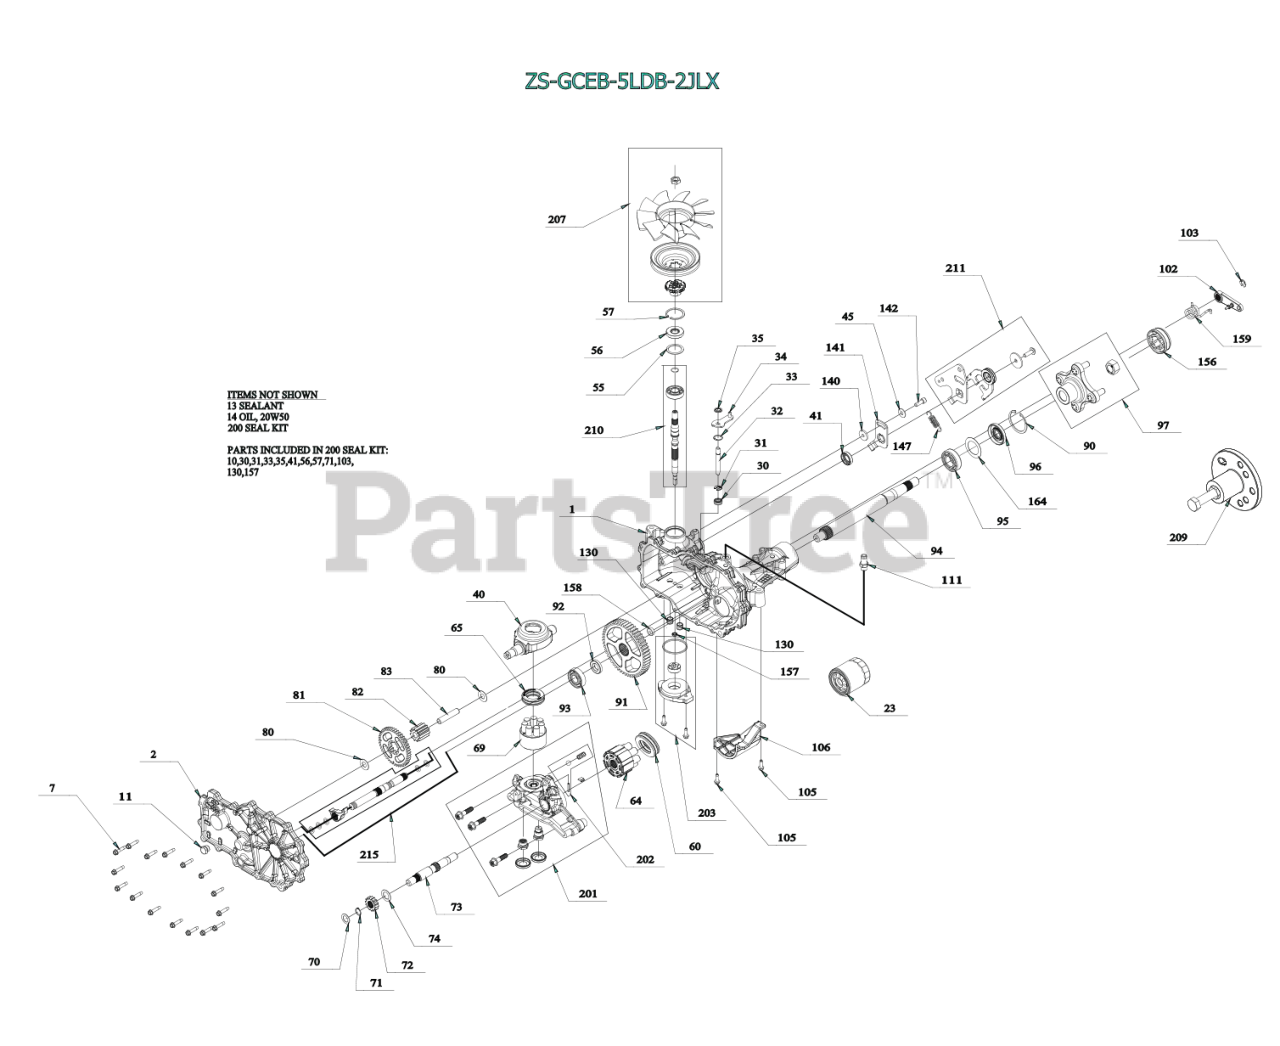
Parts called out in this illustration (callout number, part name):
1	KIT, MAIN HOUSING, RH, CHARGE, CONTROL
2	KIT, SIDE COVER RH
7	SCREW,HEX WASHER 1/4-20X1.125
23	OIL FILTER, TRANSMISSION
30	SEAL, LIP .375X.75X.25
31	RING. RETAINING
33	RING, RET .750
34	ARM, BYPASS
35	RING, RTNG .
40	TRUNNION, SWASHPLATE
41	SEAL, LIP 18X32X7
45	WASHER
55	WASHER 1.23X1.56X.04
56	SEAL, LIP 17X40X7
57	RING, RET 1.56 INT
60	HG THRUST BEARING (51462)
64	HG 16CC CYLINDER BLOCK (71579)
65	HG THRUST BLOCK (53502)
69	HG SEVEN PISTON BLOCK (71971)
70	WASHER .63X1.0X.05
71	RING, RET 62 EXT
72	GEAR, 14T (STEEL)
73	SHAFT, MOTOR
74	WASHER .71 X 1.16 X .04
80	WASHER .5X1.0X.032
82	GEAR, 11T (STEEL)
83	JACK SHAFT (PIN)
90	RING, RETAINING
91	GEAR, 54T
93	KIT, BEARING
94	GEAR, 54T
95	BEARING, BALL 25.4 X 52 X 15
96	SEAL, LIP
97	KIT, HUB 4 BOLT
102	BRAKE ARM HG 71957
103	CLIP,BRAKE ARM HYDROGEAR 52027
105	HFHCS 1/4-20X.75
106	GUARD, FILTER, RH
111	KIT, FITTING 1/2 BEADED 9/16
130	TUBE, CHARGE TRIPLE O - RING
141	ARM, NEUTRAL RIGHT
142	SHCS 5/16-24X1 PATCH
147	SPRING, HYDROGEAR P/N 51833
156	CAP, AXLE
157	KIT, GEROTOR SEAL
158	MAGNET, RING
159	SPRING, TORSION, CW
164	WASHER, 1.355 X 2.035 X .021 FLAT
200	HG SEAL KIT (71976)
201	KIT, CENTER SECTION, RH CHARGE
202	KIT, CHARGE RELIEF
203	KIT, CHARGE PUMP
207	KIT, FAN/PULLEY
209	HUB PULLER 5 BLT
210	INPUT SHAFT HG 71978
211	KIT, RTN BIDIRECTIONAL
215	KIT, OUTBOARD, RH ROT A / LH ROT B
